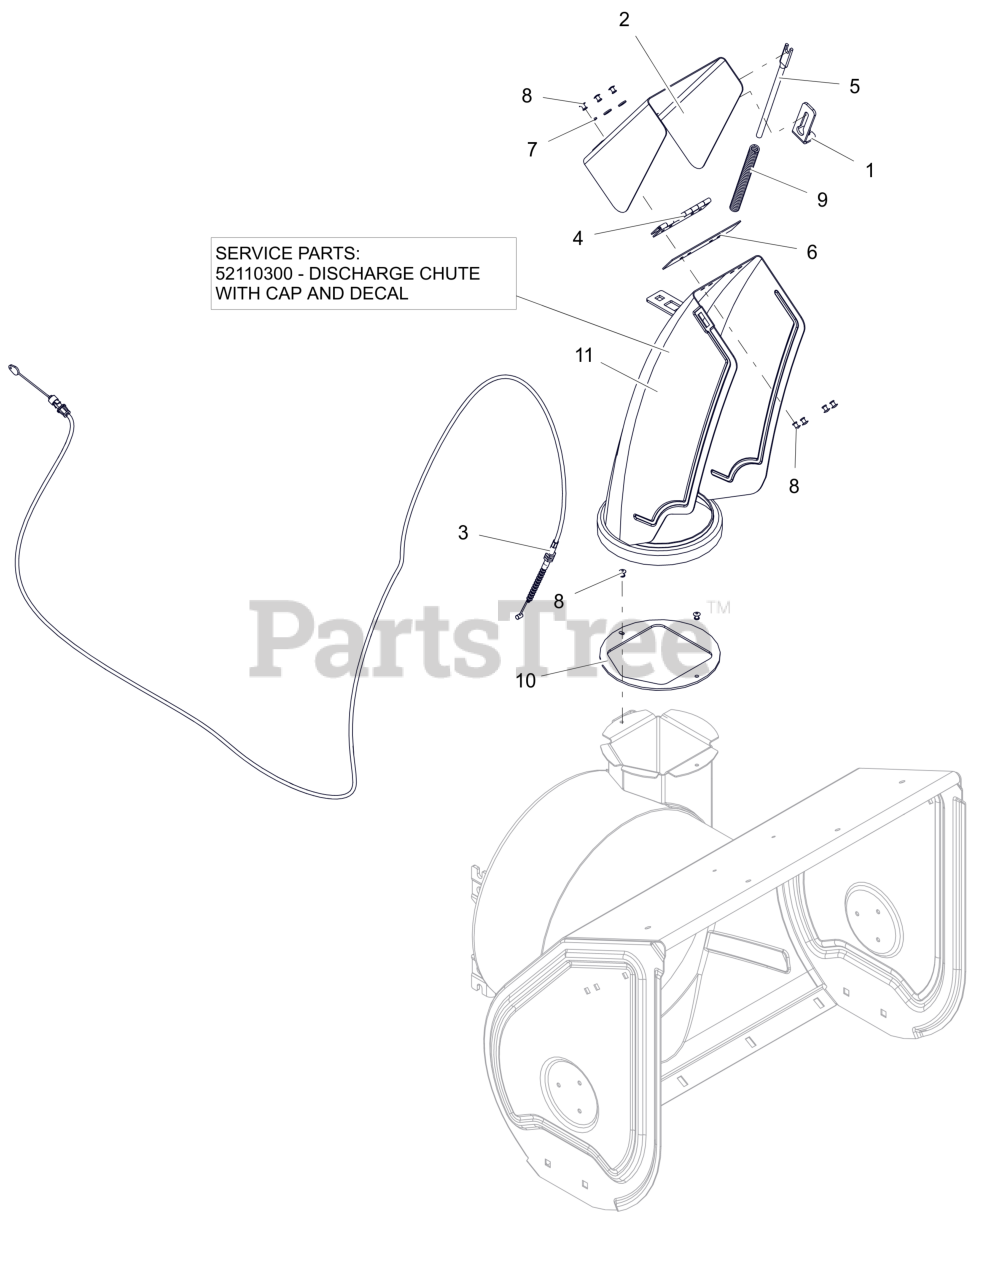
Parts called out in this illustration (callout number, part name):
1	BRKT, ANCHOR - CABLE
2	CAP, LARGE REMOTE W/DECAL
3	CABLE, DEFLECTOR - DELUXE
5	ROD, DEFLECTOR CAP
6	CAP SEAL 5.50
7	WSHR,FLT .196X.500X.066 ZCC
8	RVT, POP .1875 ZCC
9	SG-COMP .08X.40X6.50 14#/IN
10	BAFFLE, DISCHARGE NECK
11	CHUTE,DISCHARGE,RMT,ID
